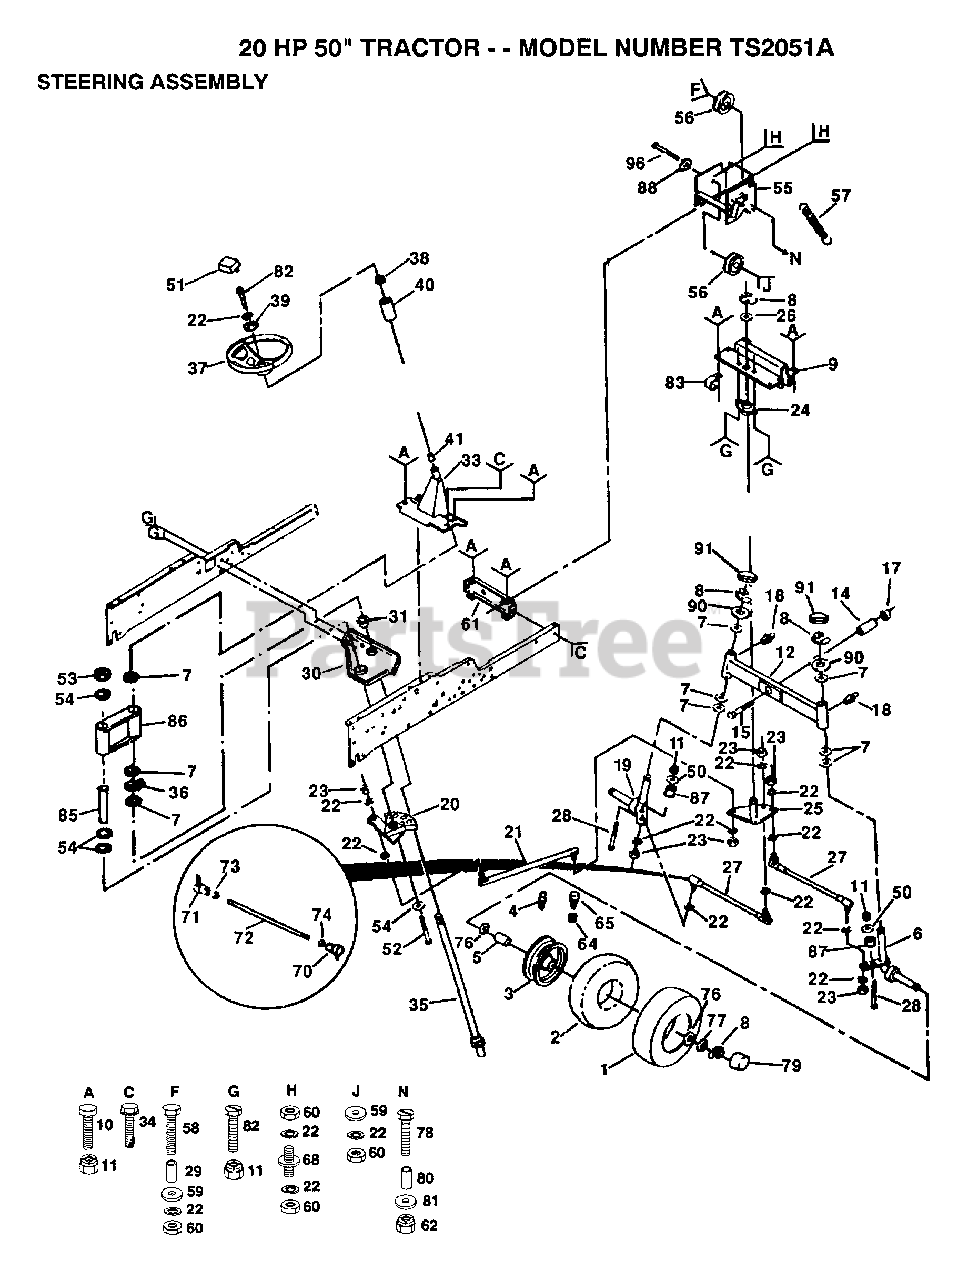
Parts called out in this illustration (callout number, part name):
2	TUBE.16X6.5/7.5-8
4	FITTING LT
5	"FLANGE, BEARING"
6	SPINDLE RH T
7	WASHER .T
8	RING
9	AXLE BRACKET T
14	SPACER BEARING
15	BOLT
17	LOCKNUT M
18	ZERK M
19	SPINDLE ASSY T
20	SECTOR T
21	LINK.DRAG.T
22	LOCKWASHER
25	"T, BELLCRANK"
26	WASHER
27	TIE ROD T
28	BOLT
29	SPLIT SPACER YTV
31	"FLANGE GT, BEAR."
33	SUPPORT ASSY T
34	SCREW
35	SHAFT STEERING GT
36	KLIP RING
38	ADAPTER LT
39	WASHER T
40	SLEEV-STEERIN T
41	"T, BEARING"
50	WASHER T
51	ST WHL INSERT CAP
52	BOLT T
53	NUT LTV
54	WASHER GT
55	IDLER BRKT T
56	IDLER-INSIDE T
57	SPRING
58	BOLT
59	WASHER
60	NUT.HEX.3/8-16UNC
61	FRAME BRACKET GT
64	VALVE STEM LT
65	VALVE CAP
70	JOINT.RH
71	JOINT.LH
73	NUT
74	NUT
76	WASHER
77	WASHER
79	HUB CAP
80	BUSHING LT
81	WASHER
82	BOLT
83	CLIP GTV
85	TUBE T
86	COLLAR
87	SPACER LT
88	WASHER T
90	WASHER
91	CAP
